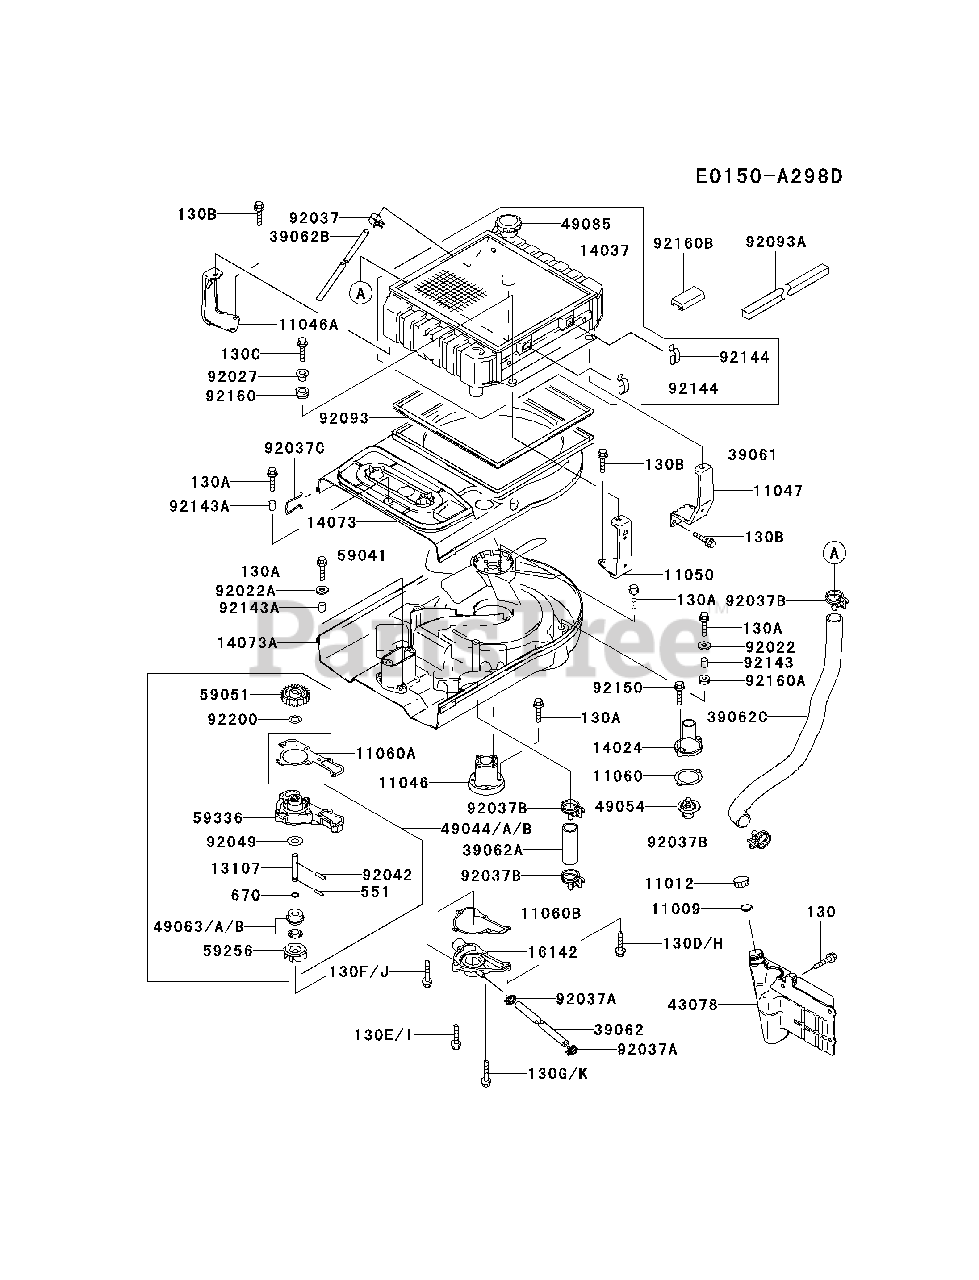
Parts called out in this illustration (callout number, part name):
130	BOLT-FLANGED,6X14
130A	BOLT-FLANGED,6X20
130B	BOLT-FLANGED,8X16
130C	BOLT-FLANGED,8X25
130D	BOLT-FLANGED,6X45
130E	BOLT-FLANGED,6X65
130F	BOLT-FLANGED,6X75
130G	BOLT-FLANGED,8X70
551	PIN-DOWEL,3X14
670	O RING,7MM
92150	BOLT,6X20
